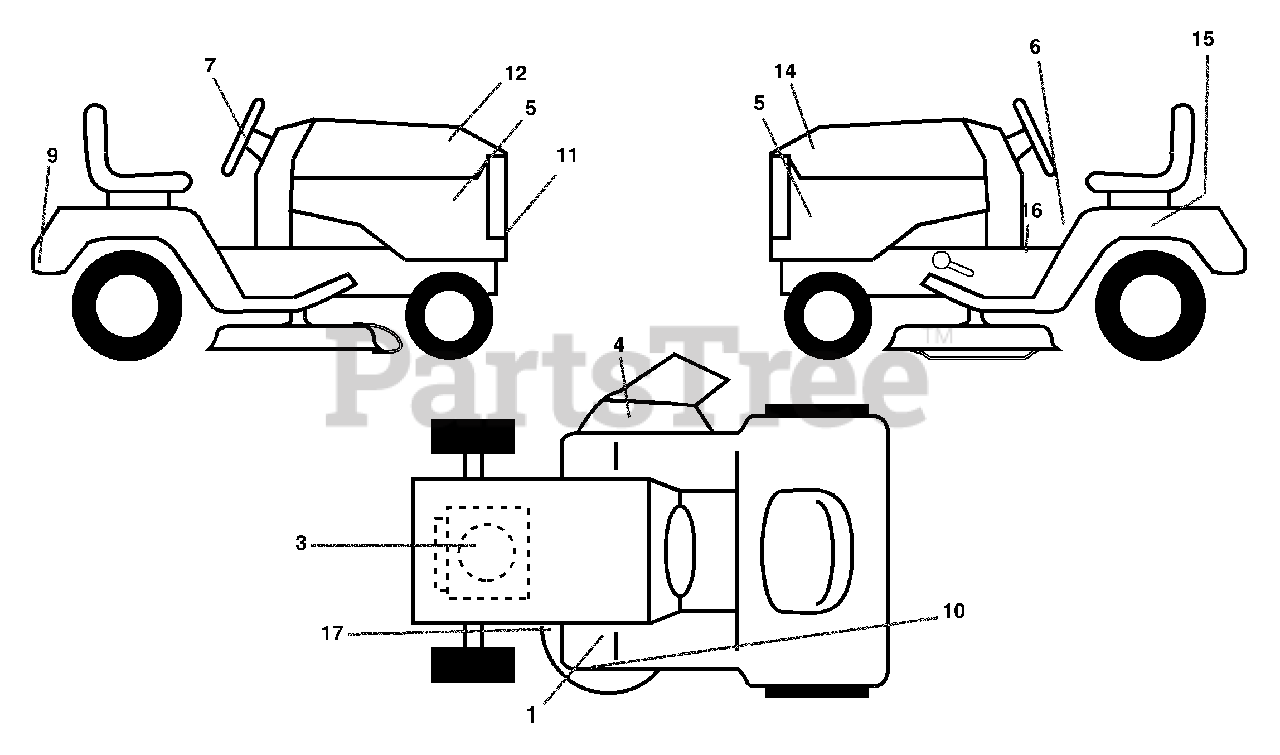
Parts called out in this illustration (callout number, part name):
1	Decal, Clutch/Brake Eng/Fr
3	Decal, Engine HP
4	Decal Warning
5	Decal, Pnl Sd
6	Decal, Fender Danger English
7	Decal Ins Str Wh
9	Decal Fender
10	Decal, Deck Grasseater
11	Decal, Grille Weedeater
12	Decal, Hood RH
14	Decal, Hood LH
15	Decal, Caution, Battery
16	Decal, Oper Sdl P/L Gear Dr Eng
17	Decal, V-Belt Sch.
